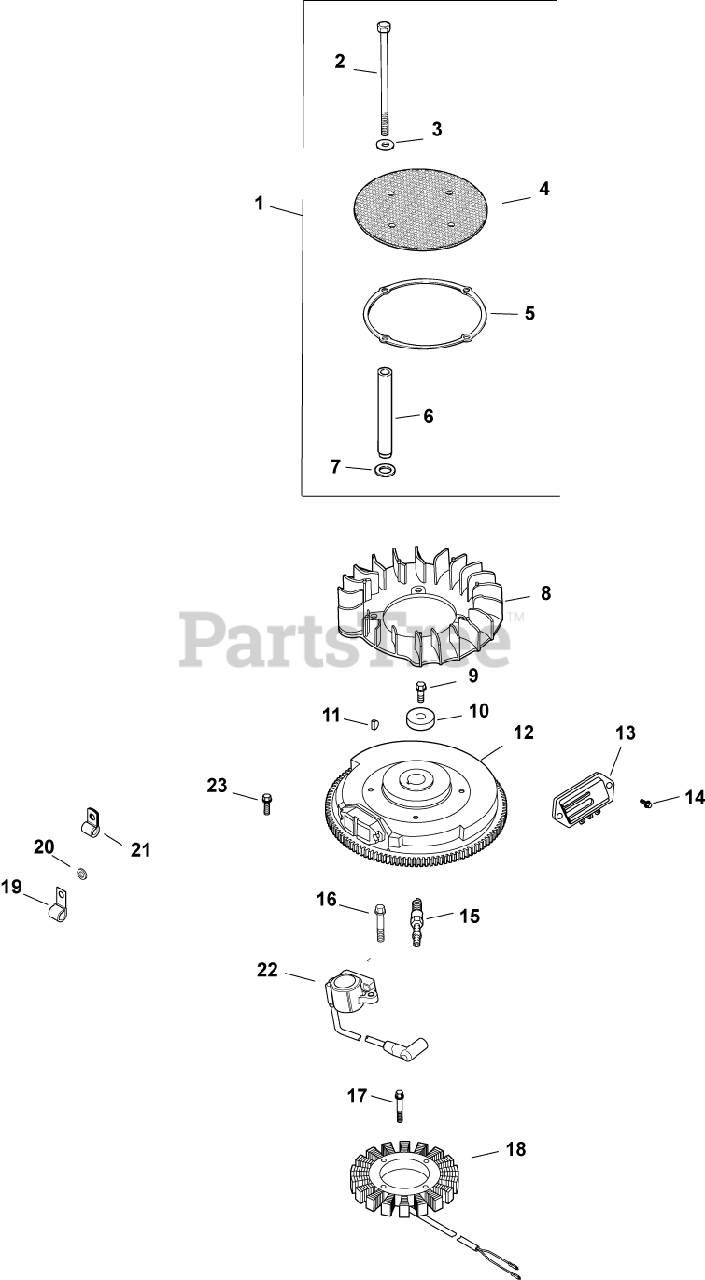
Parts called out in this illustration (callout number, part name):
1	KIT, CHOPPER SCREEN
2	SCREW, CAP M6X1.0X99.5
3	WASHER, FLAT 1/4" (O.D. 5/8")
4	SCREEN, GRASS
5	RING, SUPPORT USE 25 141 08-S
7	WASHER, SPRING 10 MM
9	SCREW, FLG M10X1.5X45 - (#25086361S)
10	WASHER, FLAT 13/32"
11	KEY, 3/16" X 5/8"
13	REG/RECT-15 AMP (KM)-USE 41 403 10-S
14	SCREW, HEX FLANGE HI-LO
15	PLUG, SPARK (STD)
16	SCREW, M5X0.8X25 - (#25086402S)
17	SCREW, SKT SET #10-24X1/4"
18	KIT, 15 / 20 AMP STATOR
19	CLIP, TUBE & WIRING (KM)
20	WASHER, FLAT 1/4" (O.D. 1/2")
21	CLIP, CABLE
22	KIT, MODULE IGNTN (CDI FIXED)
23	SCREW, FLG THD FRM M5X.8X20-(#25086399S)
